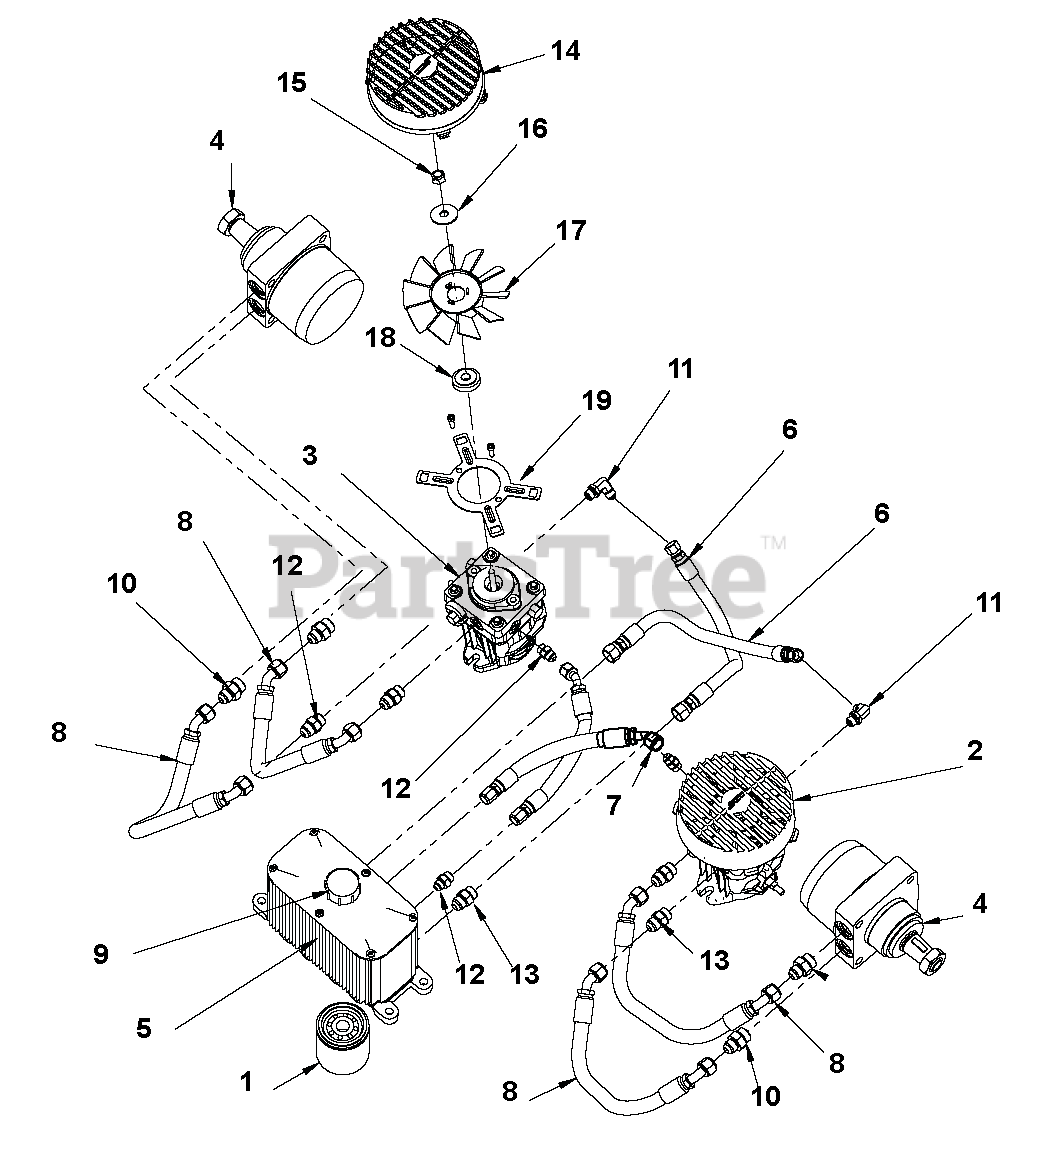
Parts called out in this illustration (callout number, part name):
1	FILTER, 25 MICRON
2	PUMP, HYDRO LH
3	PUMP, HYDRO RH
4	PARKER TJ WHEEL MOTOR TL195
5	TANK, HYDRAULIC
6	HOSE, HYD-6 -9FJIC -12FJIC 15
7	HOSE, HYD--6 -9FJIC45 7
8	HOSE, HYD-8 -12FJIC45 18
9	CAP, HYDRAULIC TANK S/O
10	ADAPTER, HYD ST 7/8 "O" TO 3/4
11	ADPT 2503-6-6
12	FTG, ADP 9/16MORX9/16MJIC
13	FTG, ADP 3/4-16MORX3/4-16MJIC
14	SHROUD, HG PUMP S/O
15	LOCKNUT, 3/8-24 CROWN Y
16	WASHER, .375X1.25X.072 BLVL U
17	FAN, HORNET PUMP S/O
18	HUB, BDP16 FAN
19	PLATE, FAN SHROUD MOUNT S/O
20	KIT, HORNET PG PUMP SEAL S/O
21	KIT, HORN WHEEL MOTOR SEAL S/O
